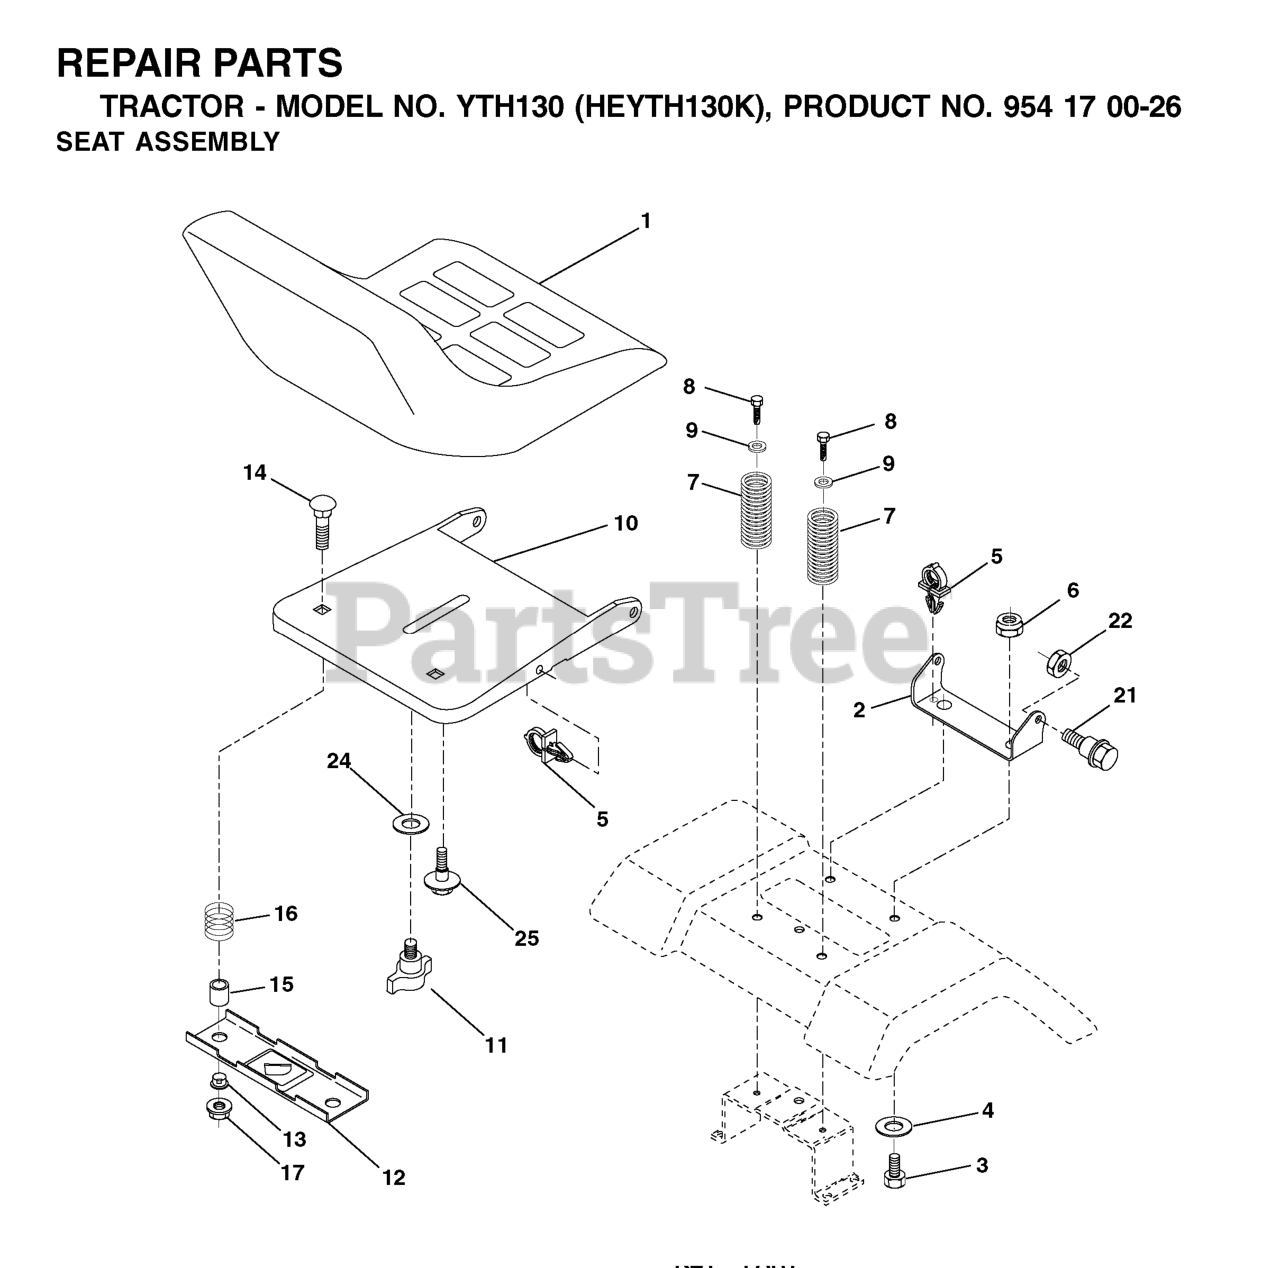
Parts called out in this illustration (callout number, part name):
1	SEAT, GRAY
2	SEAT PIVOT BRKT
3	BOLT, HEX 3/8-16X1
6	NUT
7	SPRING COMPRESSION
8	SCREW 3/8-16X1
9	WASHER
10	PAN, SEAT
11	KNOB.SEAT.ADJ.WINGNUT
12	BRKT SWITCH
14	BOLT.ROUND.HEAD.SQUARE.NECK
15	SPACER SPLIT 28X.96
17	NUT T
21	BOLT.SHOULDER.5/16-18
22	NUT.71038.31-18.HEX.NYLOCK
24	WASHER GT
25	BOLT,SHOULD
